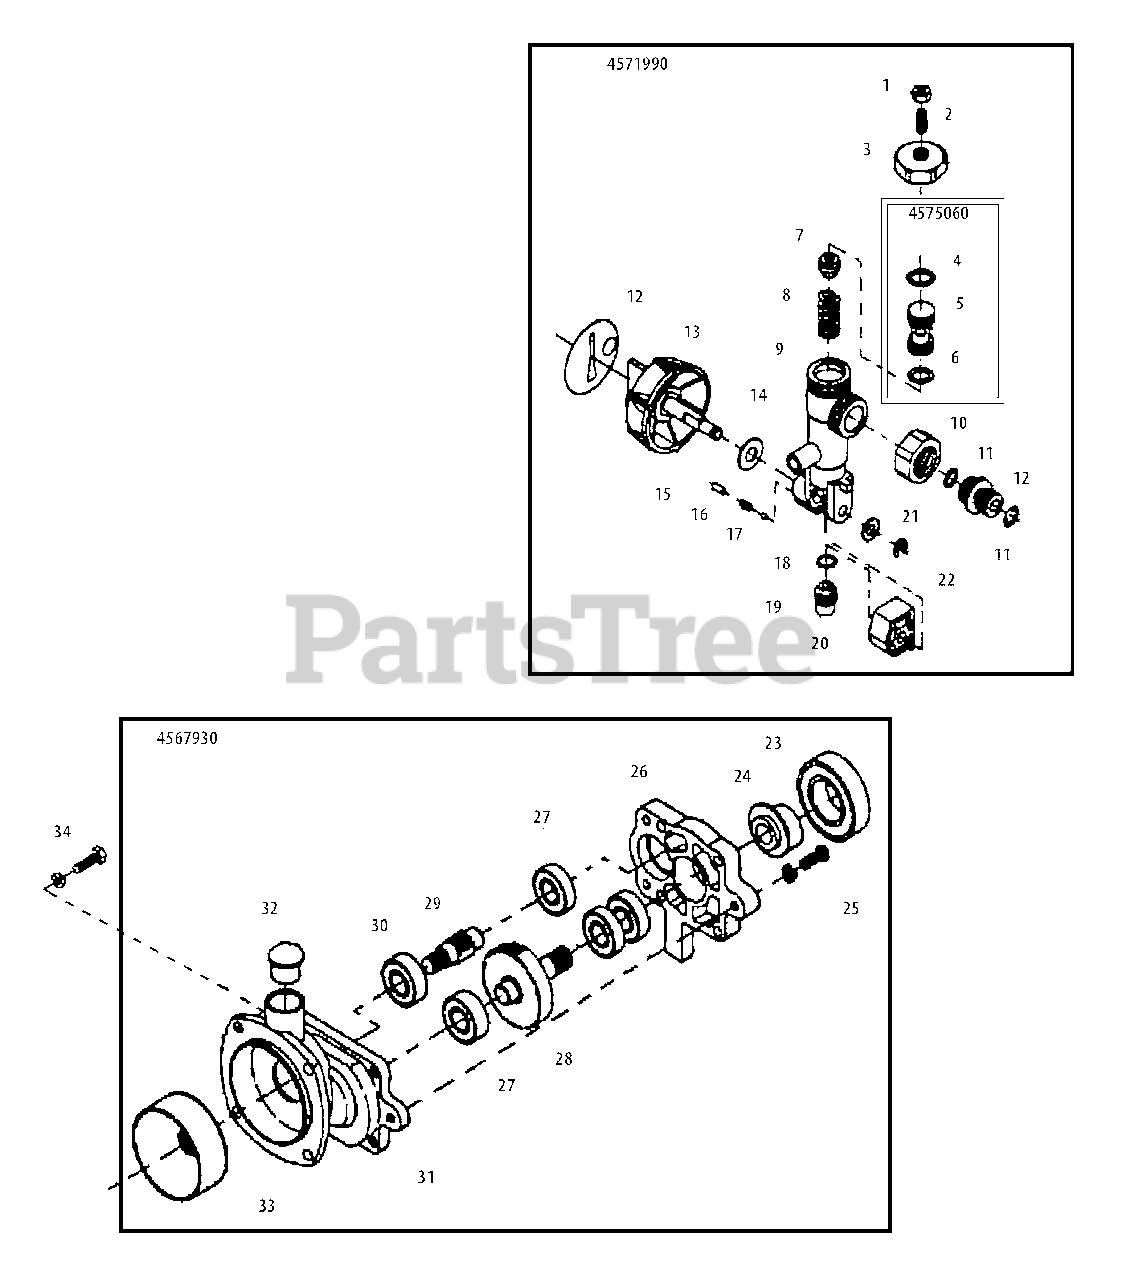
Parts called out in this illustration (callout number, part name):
3	NUT
4	O-RING
5	SEAT, VALVE
6	O-RING
7	VALVE
8	SPRING, VALVE
9	BODY, VALVE
10	NUT, LOCK
11	O-RING
12	SEAL, VALVE
14	NUT, LOCK
15	SPACER
16	SPRING
18	O-RING
21	WASHER
22	E-RING
23	BEARING, BALL
24	CRANK
25	SCREW
26	CASE, BEARING
27	BEARING, BALL
28	GEAR, CRANK
29	GEAR, DRIVE
30	BEARING, BALL
31	CRANKCASE
32	CAP
33	DRUM, CLUTCH
4567930	GEAR CASE ASSY
4571990	VALVE ASSY
4575060	VALVE SET
